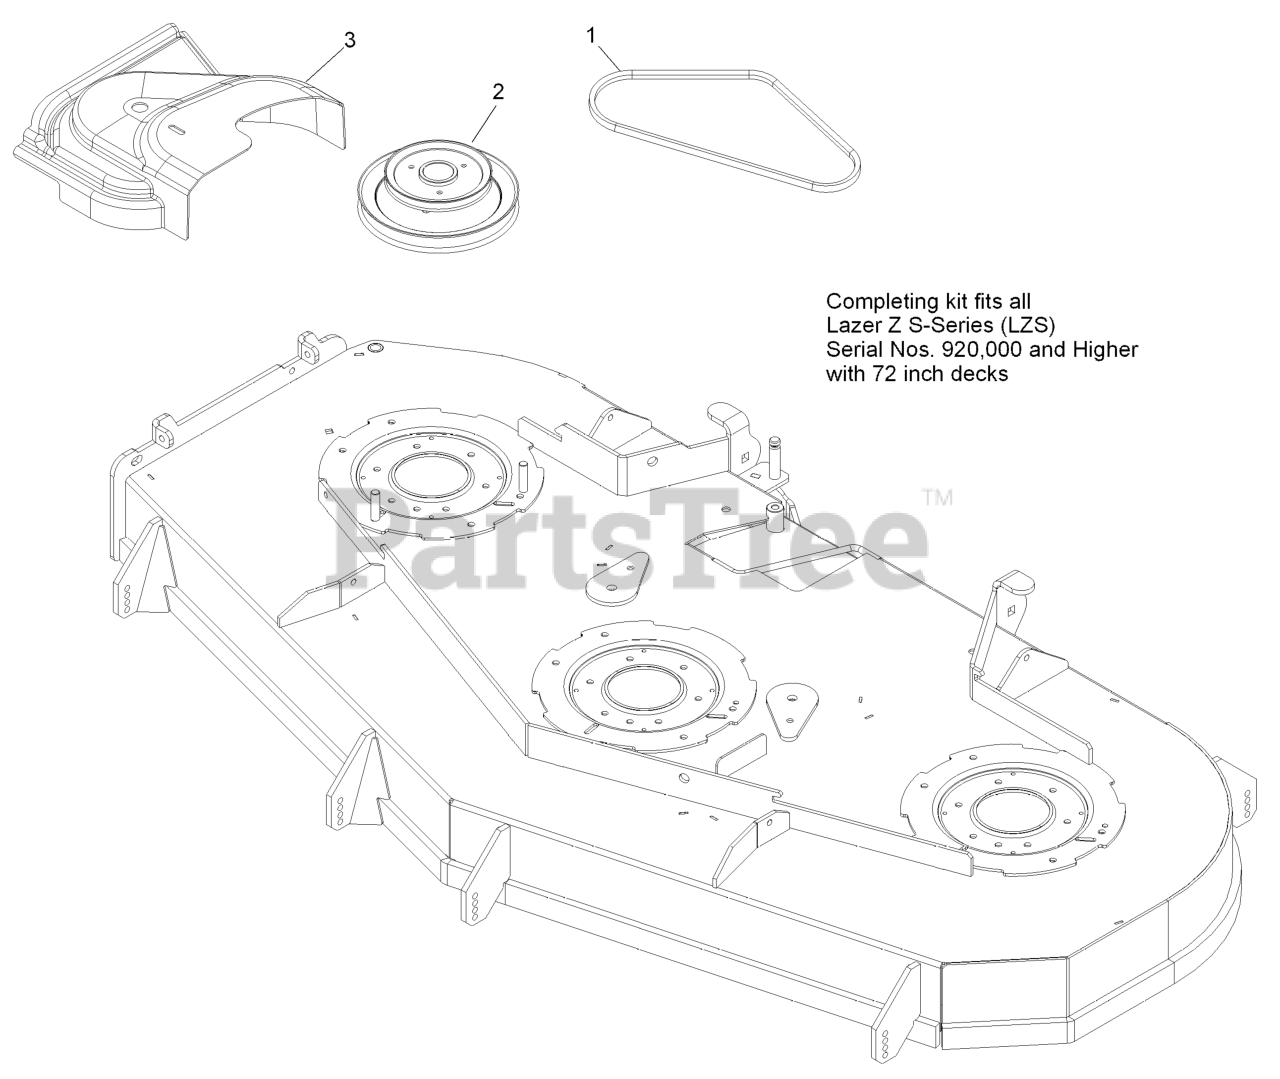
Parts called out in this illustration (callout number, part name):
1	BELT, BLOWER DRIVE 72
2	JACKSHAFT,UV DRIVE 724 SPLINED
3	COVER,BELT UV 72
